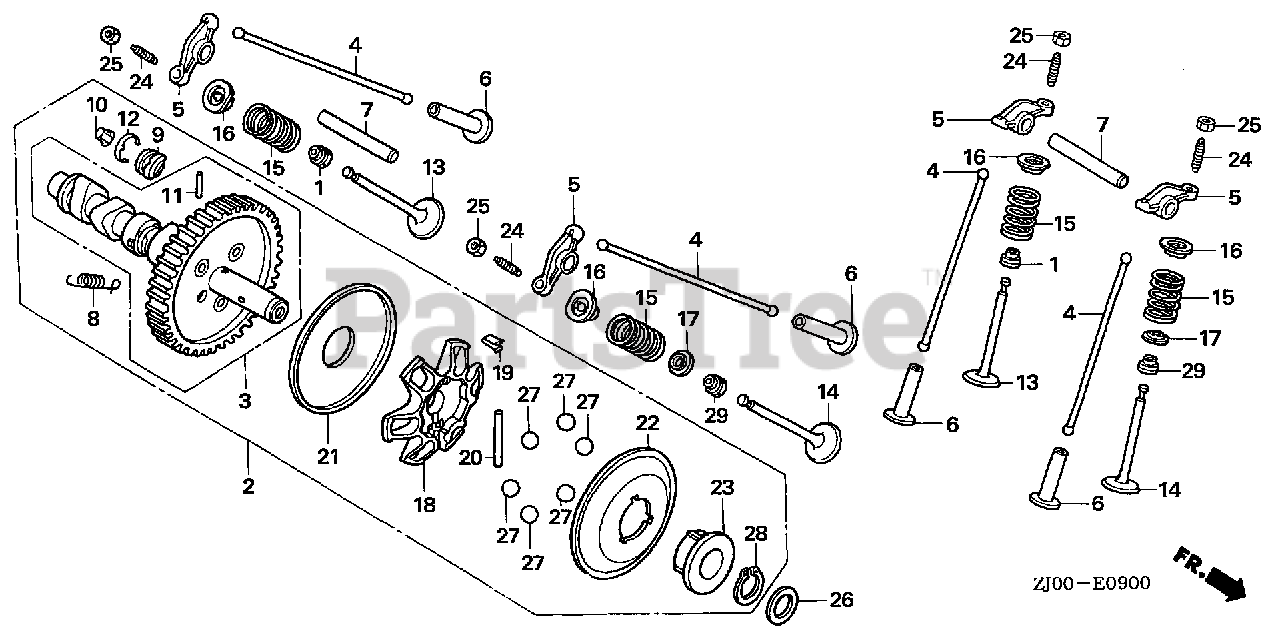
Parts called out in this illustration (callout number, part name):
1	SEAL, VALVE STEM
2	CAMSHAFT ASSY.
3	CAMSHAFT
5	ARM, VALVE ROCKER
6	LIFTER, VALVE
7	SHAFT, ROCKER ARM
8	SPRING, WEIGHT RETURN
9	HOLDER, DECOMPRESSION PIN
10	PIN A, DECOMPRESSION (7.85)
10	PIN B, DECOMPRESSION (7.95)
10	PIN C, DECOMPRESSION (8.05)
10	PIN D, DECOMPRESSION (8.15)
10	PIN E, DECOMPRESSION (8.25)
11	ROD, DECOMPRESSION
12	SPRING, DECOMPRESSION PIN HOLDER
13	VALVE, IN.
14	VALVE, EX.
15	SPRING, VALVE
16	RETAINER, IN. VALVE SPRING
17	SEAT, VALVE SPRING
18	HOLDER, GOVERNOR WEIGHT
19	PLATE, GOVERNOR WEIGHT HOLDER
20	PIN, GOVERNOR WEIGHT HOLDER
21	PLATE, GOVERNOR (LOWER)
22	PLATE, GOVERNOR SLIDER
23	SLIDER, GOVERNOR (NOT AVAILABLE)
24	SCREW, TAPPET ADJUSTING
25	NUT, TAPPET ADJUSTING
26	WASHER, THRUST (17.2MM)
27	BALL, STEEL (18)
28	CIRCLIP (OUTER) (17MM)
29	SEAL, VALVE STEM
